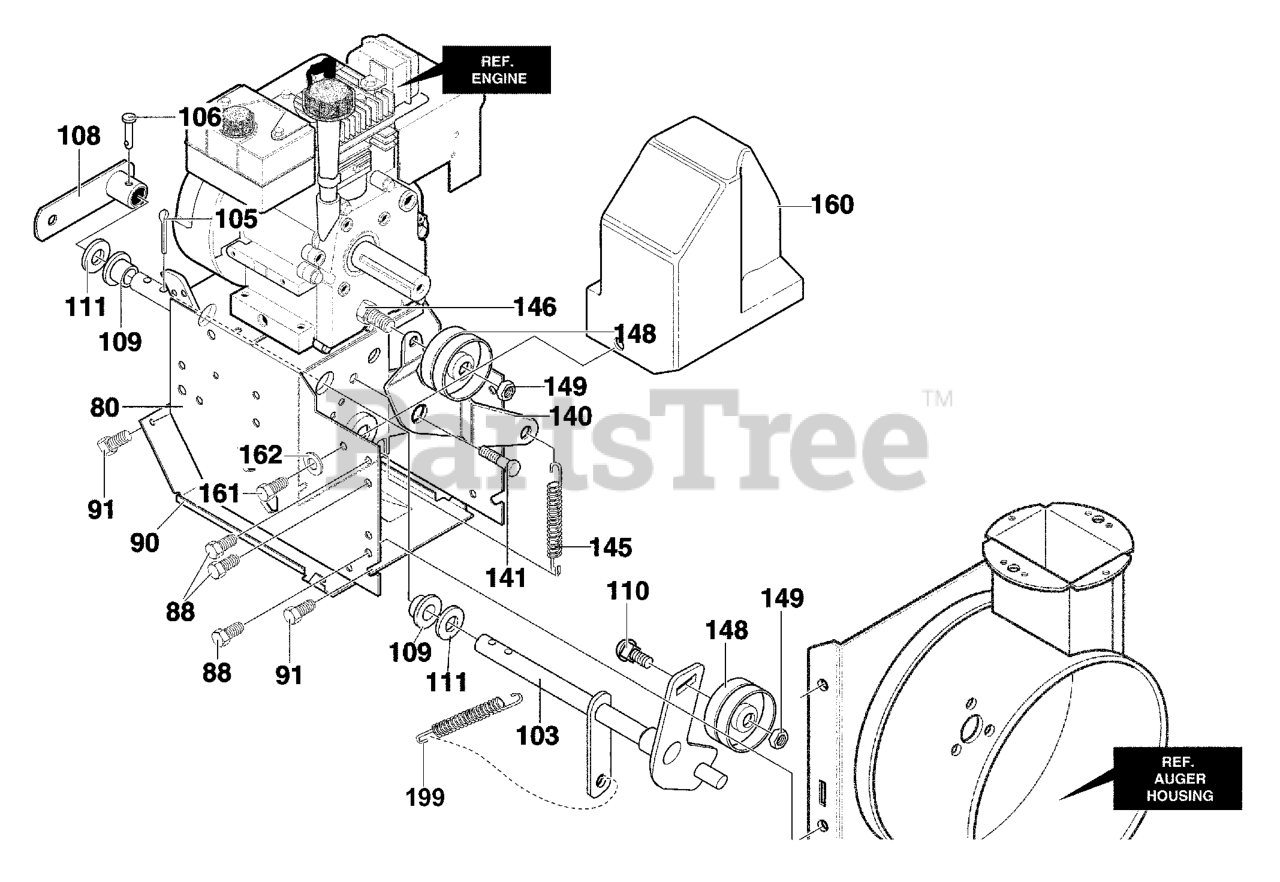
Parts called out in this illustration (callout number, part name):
80	FRAME ASSY
88	SCREW, 5/16-18 x 0.50
90	COVER, BOTTOM
91	SCREW, 1/4-20X .63
103	IDLER ASSEMBLY
105	PIN, HAIR .38DIAX1.64LG
106	PIN, KLIK 3/16" DIA
108	ASSY., SPRING ATTACH
109	BEARING, FL.
110	BOLT, 3/8-16X1.25 CARR.
111	WASHER, FLAT
140	LEVER, IDLER ARM TRACTION
141	BOLT, .625X.135 HHSH 5/16-18
145	IDLER SPRING TRACTION DRIVE
146	SCREW, 3/8-16 x 1.25
148	PULLEY, IDLER
149	NUT, 3/8-16
160	COVER, BELT
161	SCREW, 1/4-20X .63
162	WASHER, FLAT
199	SPRING, IDLER AUGER DRIVE
